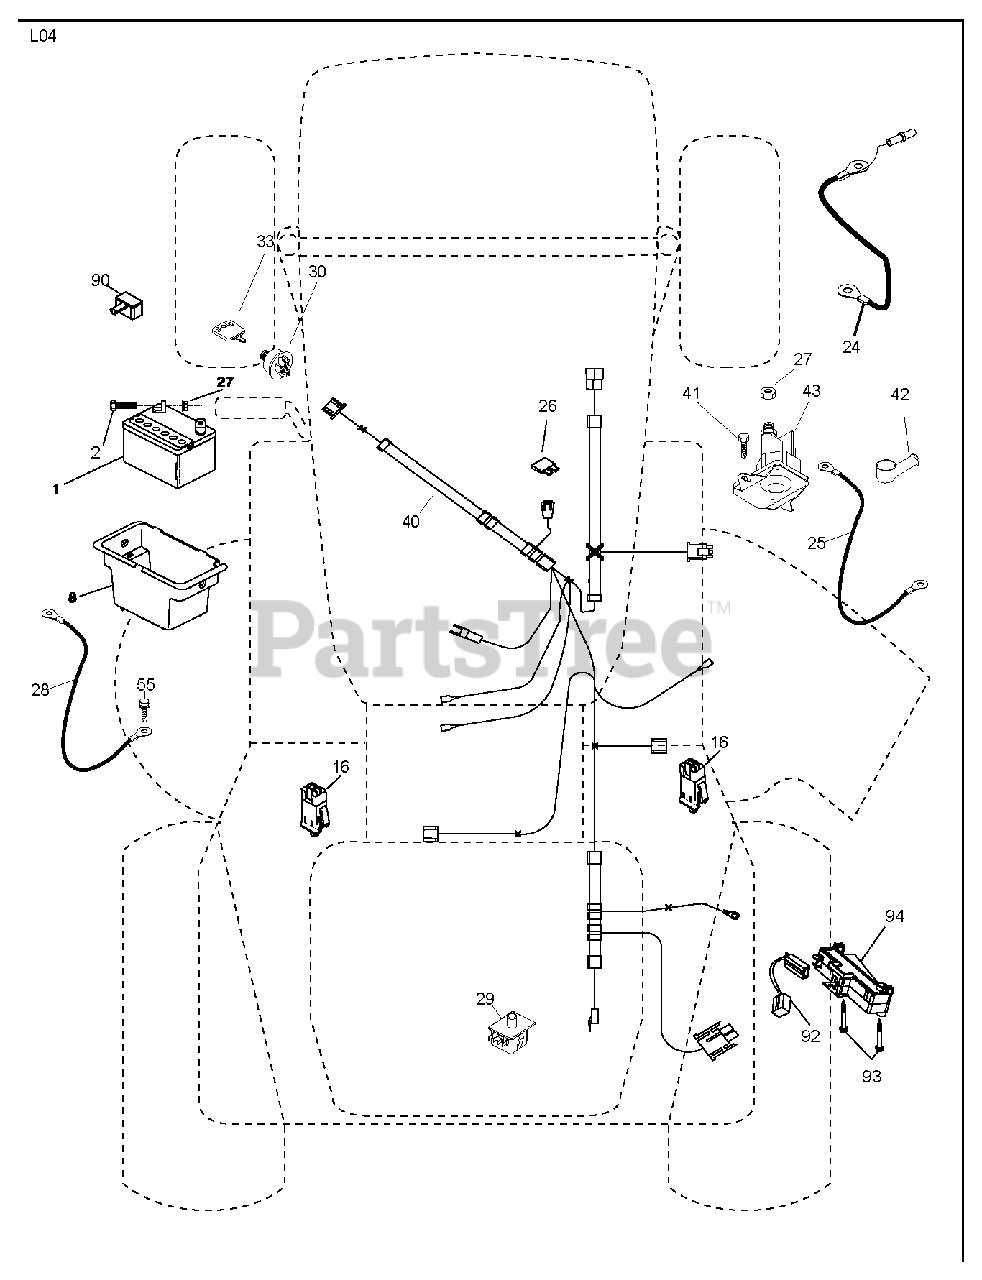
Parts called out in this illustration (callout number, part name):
1	REPL BY 532 12 38-99
8	BOX.BATTERY.FENDER
16	SWITCH INTERLOOK PUSH-IN
24	CABLE BATTERY 6 GA. 11" RED
25	CABLE.GROUND.REAR.BTRY.8GA.44"
27	NUT
28	CABLE GROUND 6 GA. 12" BLACK
29	SWITCH.SEAT.DP W/RAMPS
30	SWITCH.IGN.DELTA.W.LGH.ROS
33	KEY.CHAIN.BLISTER.PACK.GEN.INT
41	Hex Capscrew, 1/4-20
42	TERMINAL COVER
43	SOLENOID.W/BRASS.PLUNG
90	COVER.TERMINAL.BATTERY
92	HARNESS.PIGTAIL.CONSLE
93	SCREW.PLASTITE
94	MODULE.REVERSE.ROS
